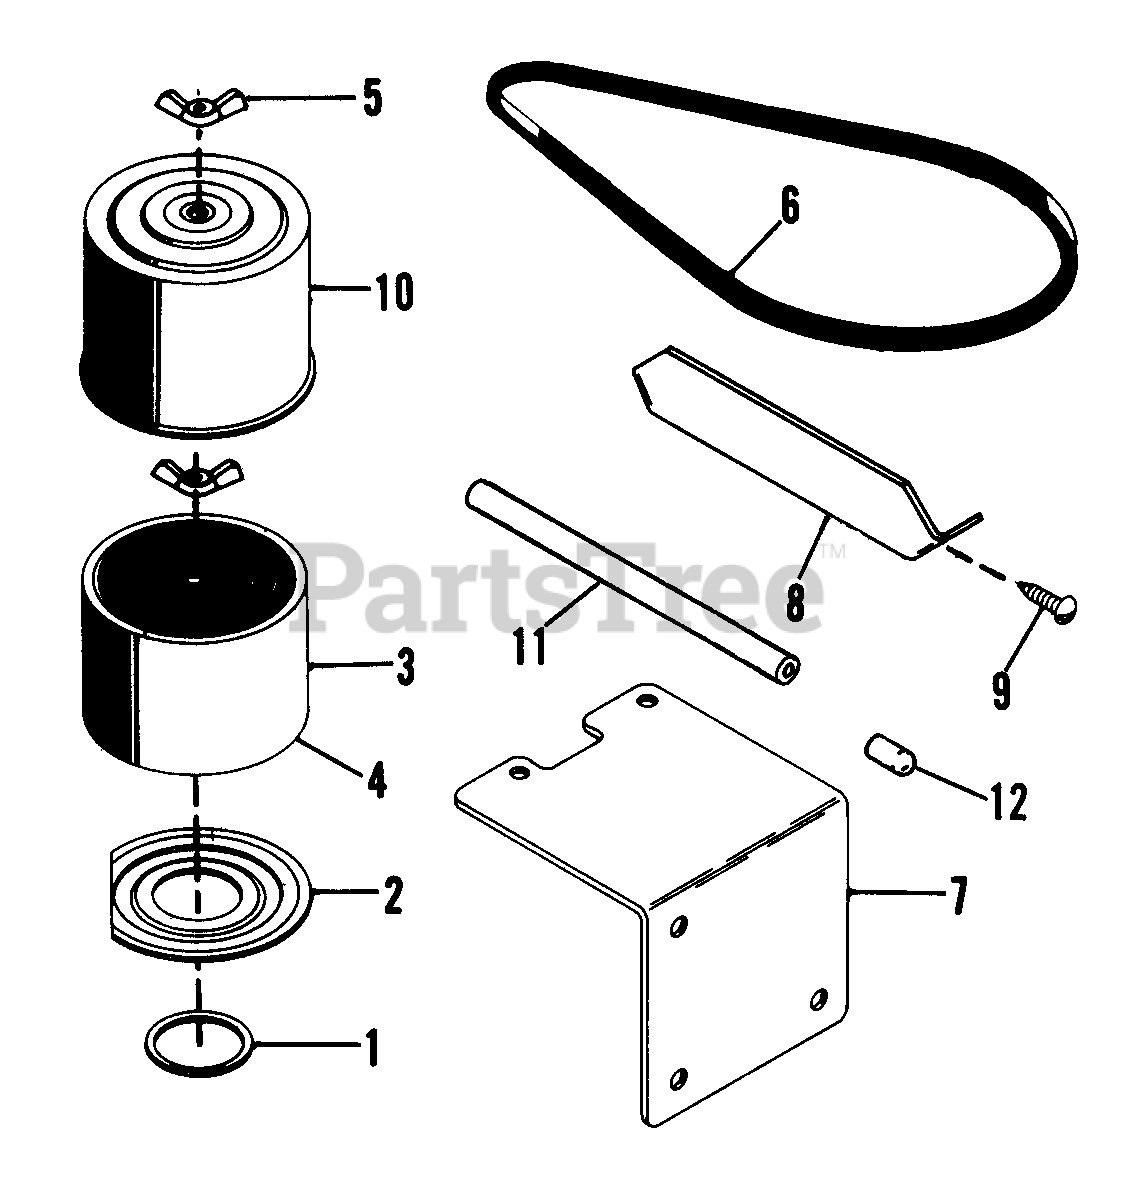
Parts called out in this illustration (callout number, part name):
1	GASKET
2	AIR CLEANER BASE
3	FOAM
4	CARTRIDGE
5	NUT-WING BRIGGS
6	V-BELT, 4L-RAW EDGE
7	SWITCH BRACKET
8	GUARD PLATE
10	AIR CLEANER COVER
11	FUEL LINE 1/4 X 16"
